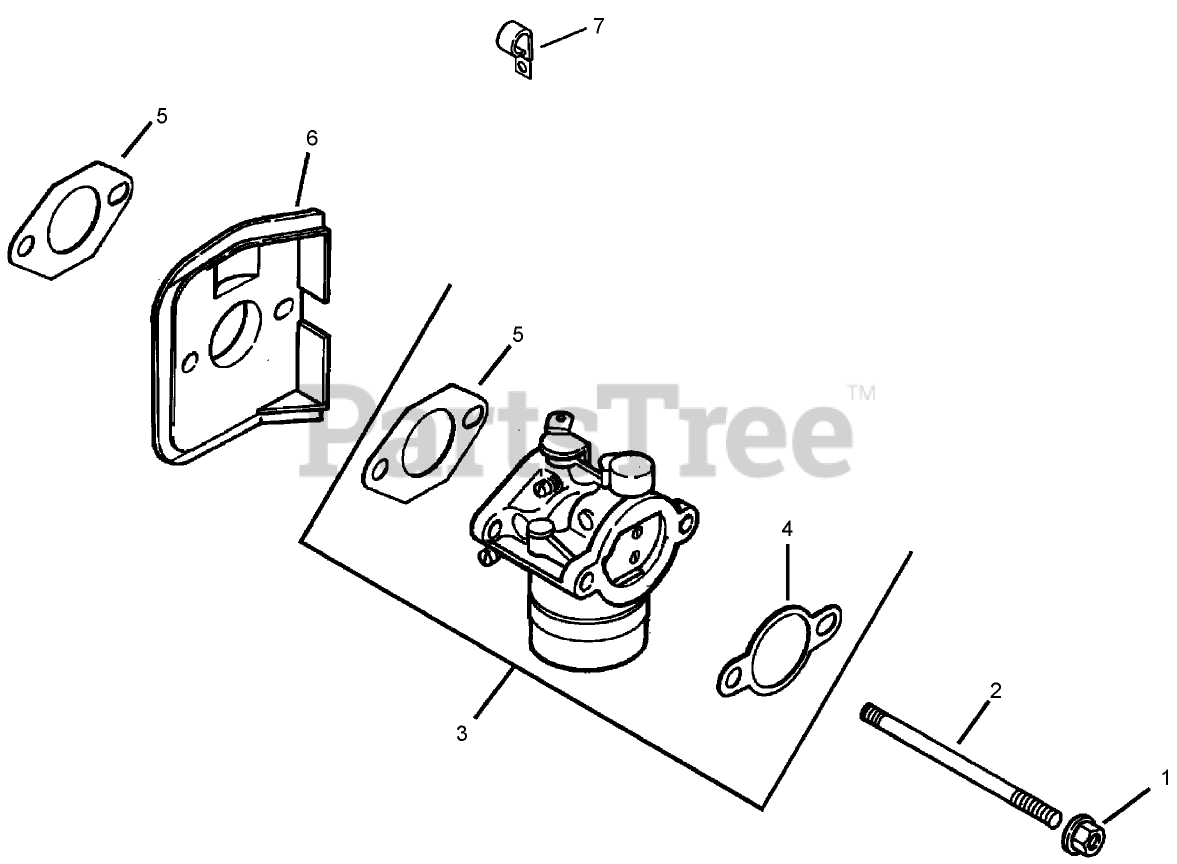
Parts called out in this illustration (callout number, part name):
1	NUT-FLANGE (M6X1.0)
2	Stud (M6x1.0x116)
3	Carburetor Kit (Includes 4-5)
4	Gasket-Base, Air Cleaner
5	Gasket-Carburetor
6	Deflector-Heat
7	CLIP-CABLE
